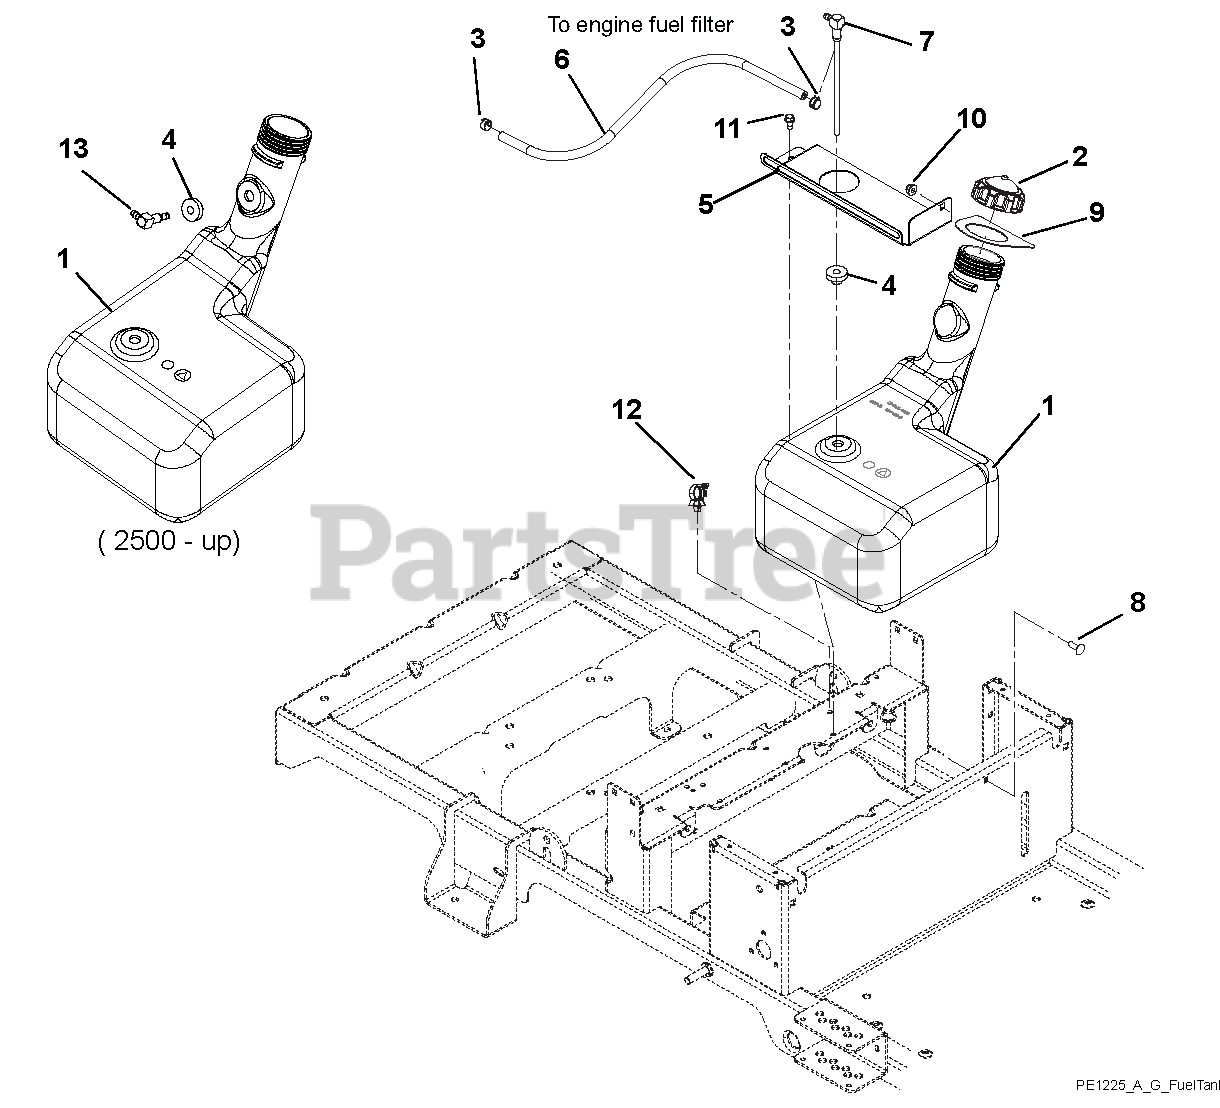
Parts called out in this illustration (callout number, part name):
1	FUEL TANK
1	TANK, ZOOM/WAW NON-PERM. FUEL
2	FUEL CAP
2	CAP, 2.25" ONE-WAY VENT FUEL
3	CLAMP, FUEL LINE
4	BSHG-FLG .375X1.062X.625 NITR
4	Bushing (Serial Number 2500 - up)
5	BRKT, TANK STRAP
6	HOSE, .25 LOW-PERM BULK GAS
7	FUEL PICK UP TUBE
8	@BLT-RDHDSQNK .25-20X.75 G5YZ
9	SEAL-TANK NECK
10	@NUT-LK-NYL-FLG .25-20 YWZC
11	SCR-TAP .25-20X.50 HWH TR YWZ
12	WIRE CLIP
13	FITTING, 90 DEG FUEL (PLASTIC)
